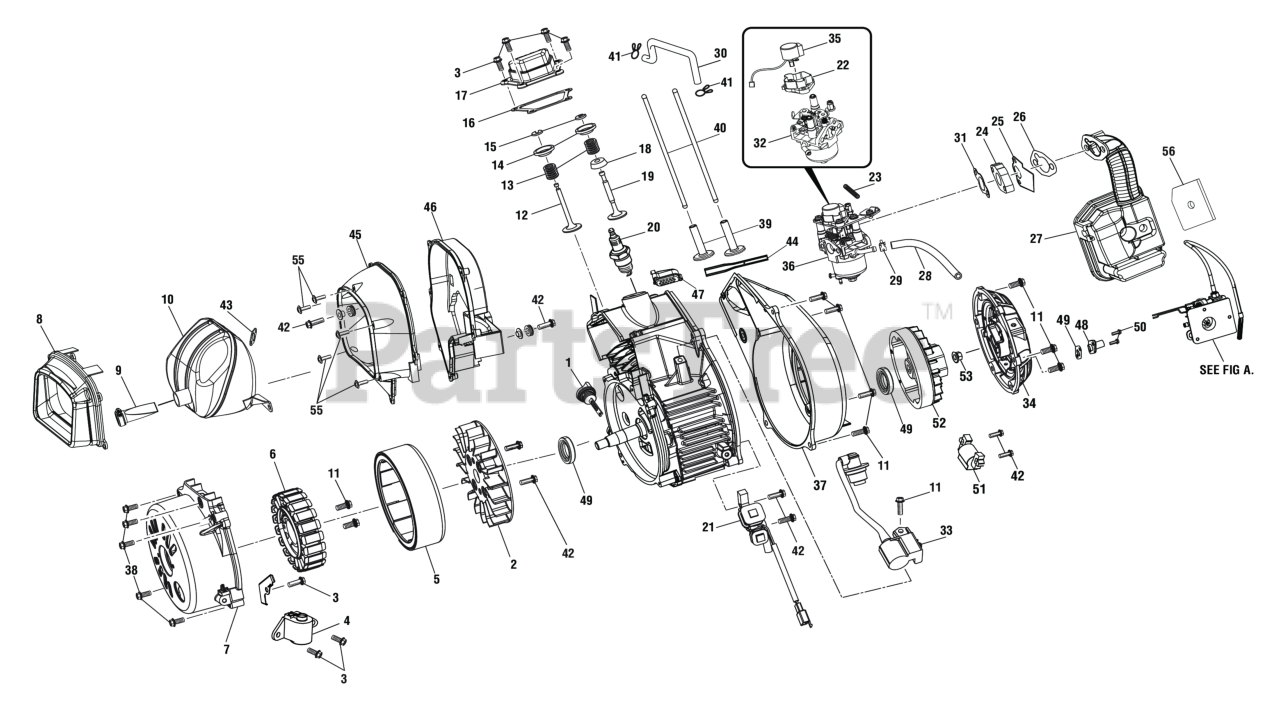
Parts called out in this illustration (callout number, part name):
1	Oil Dipstick
3	Bolt (M6 x 12 mm)
4	Low Oil Sensor
7	Alternator Cover
8	Muffler Heat Shield
9	Spark Screen
11	Bolt (M6 x 16 mm)
12	Exhaust Valve
13	Valve Spring
15	Valve Lock Clamp
16	Gasket (Over Head Cover)
17	Over Head Cover
18	Inlet Valve Spring Seat
19	Inlet Valve
20	Spark Plug
21	RPM Sensor
22	Governor Motor Housing
23	Compression Spring
24	Thermal Insulation Seat (Carburator)
25	Paper Gasket
26	Air Box Gasket
27	Air Filter Assembly
28	Fuel Hose (6 mm)
29	Fuel Line Clamp (7/16 in., BM903611)
30	Breather Pipe
31	Gasket (Muffler)
32	Carburetor
33	Ignition Coil
34	Engine Recoil
35	Stepper Motor
36	Carburetor Assembly (Inc. Key Nos. 22, 32 and 35)
37	Engine Cover
38	Bolt (M6 x 30 mm)
39	Lifter Valve
40	Pushing Rod
42	Bolt (M6 x 20 mm)
43	Gasket (Connection Block)
44	Breather Hose
45	Muffler Cover 1
46	Muffler Cover 2
47	Fill Valve Assembly
48	Ring Flange
49	Oil Ring
50	Bolt (M5 x 12 mm)
51	Magneto Ignition
52	Flywheel
53	Flywheel Nut
54	Oil Seal
56	Air Filter
